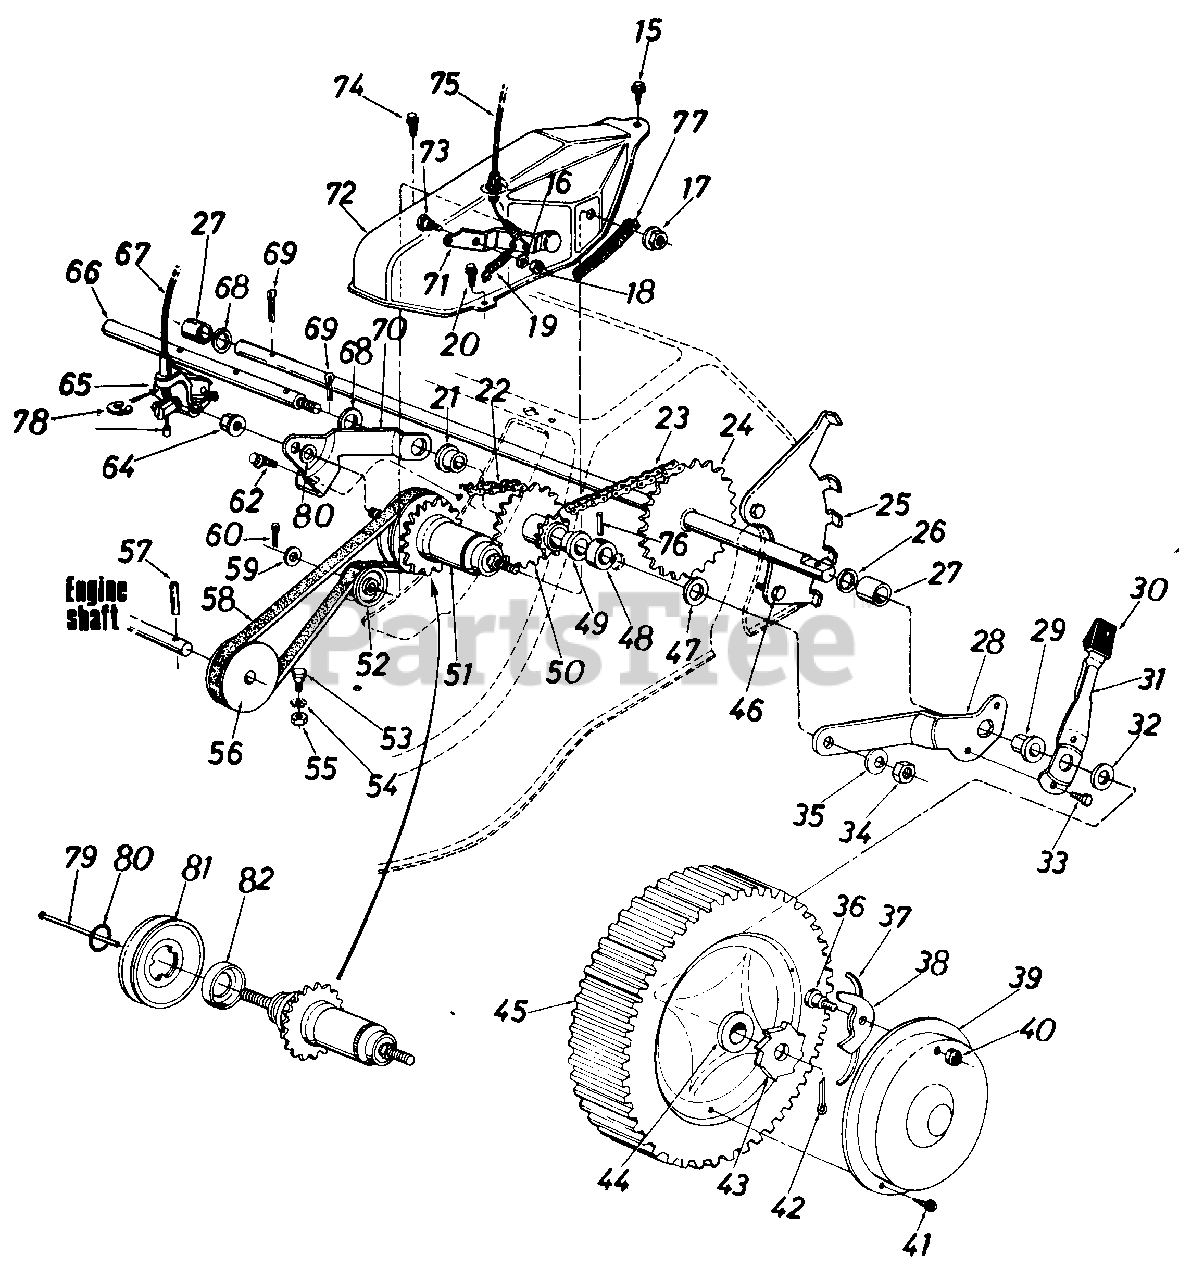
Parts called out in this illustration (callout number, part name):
15	Hex Drilling Scr. #10 x .50" Lg.
16	L-Wash. 1/4" I.D.*
17	Hex Nut 3/8-24 Thd.
18	Hex Nut 1/4-20 Thd.*
19	Extension Spring .33" O.D. x 1.12" Lg.
20	Hex Wash. S-Tap Scr. 1/4-20 x .50" Lg.
21	Flg. Brg. .506" I.D. Plastic
22	#48 Chain 1/2" Pitch x 38 Links (Endless)
23	#48 Chain 1/2" Pitch x 32 Links (Endless)
24	Rear Shaft Ass'y. 20.75" Lg.
25	Index Plate Rear L.H.
26	Fl-Wash. .510" I.D. x 1.0" O.D.
27	Spacer.740" I.D. x .83" O.D.
28	Pivot Brkt. L.H.
29	Hex Flange Brg. .506" I.D. Plastic
30	Spring Lever Knob
31	Spring Lever
32	Fl-Wash. .531" I.D. x .930" O.D.
33	Hex B-Tap Scr. 1/4 x .38" Lg.
34	Hex Jam N ut 3/8-16 Thd.
35	Bell-Wash. .400" I.D. x .88" O.D.
36	Shld. Bolt .342" Dia. x .268
37	Spring Nylon
38	Pawl
40	Hex Ins. L-Nut 1/4-20 Thd.
41	Pan Hd. Tap Scr. #12 x .50" Lg.*
42	Cotter Pin 1/8" Dia. x 1.00" Lg.*
43	Ratchet Wheel 1.62" O.D.
44	Fl-Ball Brg. 1/2" I.D.
45	Wheel Ass'y. Comp. 8 x 1 .75
46	Hex L-Wash. Hd. AB-Tap Scr. 1/4 x .62" Lg.
47	Bell-Wash. .400" I.D. x 1.13" O.D.
48	Spacer.505" I.D. x .88" O.D.
49	Flg. Brg. .506" I.D. Plastic
50	9 and 21 Tooth Sprocket Ass'y.
51	Shimano 3-Sp. Hub w/ 18 Tooth Sprocket
52	Fl-ldler Plastic 1.62" Dia.
53	Shld. Bolt .437" Dia. x .180
54	L-Wash. 5/16" I.D.*
55	Hex Nut 5/16-18 Thd.*
56	1/2" "V"-Engine Pulley .50" I.D. x 2.80" O.D.
57	Spring Pin Spir. 3/16" Dia. x 1.50" Lg.
58	"V"-Belt 1/2" x 26.0" Lg.
59	Fl-Wash. .531" I.D. x .930" O.D.
60	Cotter Pin 1/8" Dia. x 1.00" Lg.*
62	Hex Wash. Hd. Tap Scr. 5/16-18 x .75" Lg.
64	Hex Nut 3/8-24 Thd.
65	Shimano 3-Sp. Shift Bell Crank
66	Pulley Shaft 10" Lg.
67	Shimano 3-Sp. Solid Shift Cable
68	Fl-Wash. .531" I.D. x .930" O.D.
69	Cotter Pin 3/32" Dia. x 1.00" Lg.*
70	3-Sp. Hub Bracket
71	Idler Bracket Ass'y.
72	3-Sp. Belt Cover
73	Shld. Bolt .375" Dia. x .181
74	Hex TT-Tap Scr. 1/4-20 x .75" Lg.
75	S.P. Cable 53" Lg. Blue
76	Spring Pin Spir. 3/16" Dia. x1.0" Lg.
78	Snap Ring
79	Shifting Pin
80	Pulley Snap Ring
81	1/2" V-Pulley 1.375" I.D. x 3.25" O.D.
82	Shimano 3-Sp. Dust Cover
